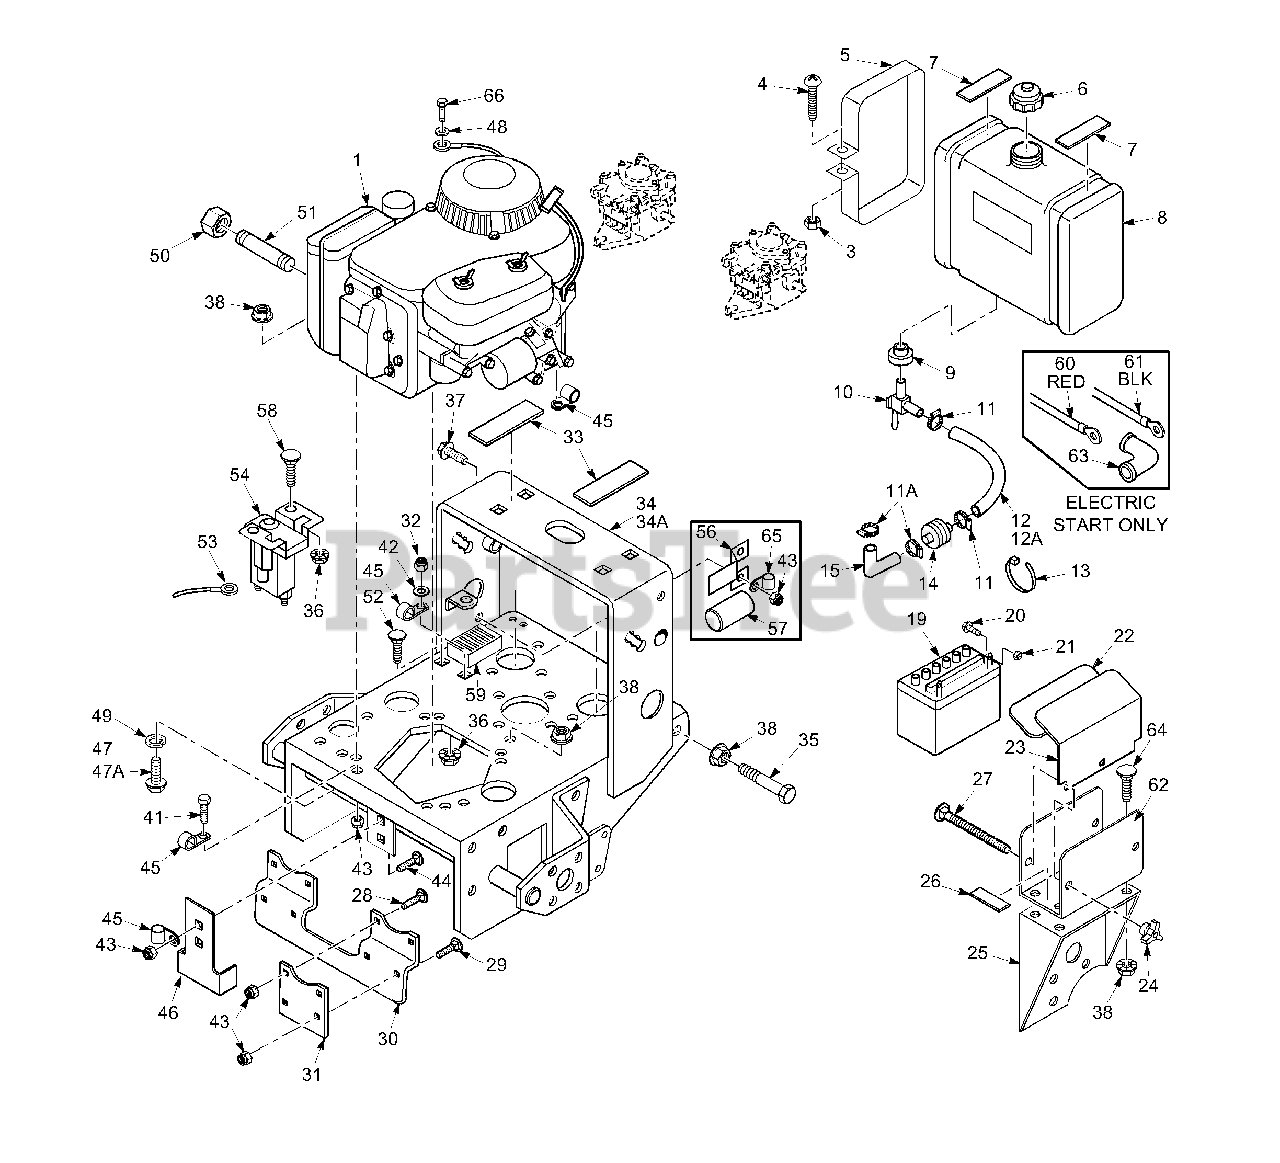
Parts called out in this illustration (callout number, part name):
1	Engine 17KA Kawasaki
2	Retaining Ring, 1/2" Ext. "E"
3	Hex Nut, 1/4-20
4	Screw, 1/4-20 x 2" Rnd. Hd. Phil.
5	Strap, Fuel Tank
6	Cap, Fuel Tank
7	Pad, Rubber-Fuel Tank - Upper
8	Fuel Tank Assy.
9	Bushing
10	Valve, Fuel Shut-off
11	Clamp, Fuel Hose
11A	Clamp, Fuel Hose
12	Fuel Hose, 1/4 ID x 20" KA
13	Cable Tie
14	Fuel Filter
15	Fuel Hose, 7/32 ID x 3-1/2"
16	Capscrew, #10-32 x 1 Soc. Hd.
17	Lever Assy., Pump Control -LH
18	Lever Assy., Pump Control -RH
19	Battery
22	Pad
23	Battery Cover
25	Battery Support
26	Pad, Rubber
27	Bolt, 1/4-20 x 6" Carriage
28	Carriage Bolt, 5/16-18 x 2"
29	Carriage Bolt, 5/16-18 x 1"
30	Stiffener
31	Plate, Backing
32	Nut, 1/4-20 Elastic Stop
33	Pad, Rubber-Fuel Tank, Lower
34	Engine Deck, 16" Wide, W/Decls.
34A	Engine Deck, 20" Wide, W/Decls.
35	Bolt,1/4-20 x 1-1/4" Hex Head
36	Nut, 1/4-20 Serrated Flange
37	Capscr., 5/16-18 x 1.25 Sr. Flg.
38	Nut, 5/16-18 Serr. Flange
39	Nut, 3/8-16 Serr. Flange
40	Bolt, 3/8-16 x 2-3/4" Hex Head
41	Hex Head Bolt, 5/16-18 x .75"
42	Flat Washer 1/4"
43	Nut, 5/16-18 Elastic Stop
44	Carrage Bolt, 5/16-18 x 1"
46	Clutch Bracket
47	Capscr, 5/16-18 x 1.50" Sr. Flg.
47A	Metric HH Bolt, M8-1.25 x M30
48	Lock Washer, 5/16 Int. Tooth
49	Lock Washer, 5/16
50	Pipe Cap
51	Pipe, 4.75" Nipple
52	Carrage Bolt, 1/4-20 x 1-1/4"
53	Wire Hrns. Adapter, 17KA
54	Pulley Guard, 16" Frame
54	Pulley Guard, 20" Frame
55	Shaft Weldment, RH Pump Cntl.
56	Bracket, Capacitor
57	Condenser (order from Kaw.)
58	Metric H H Bolt, 8-1.25 x 10
59	Regulator, (order from Kaw.)
60	Battery Cable, 31.5" Red
61	Battery Cable, 31.5 Black
62	Battery Box
63	Rubber Boot
65	Cable Clamp, .75 ID
